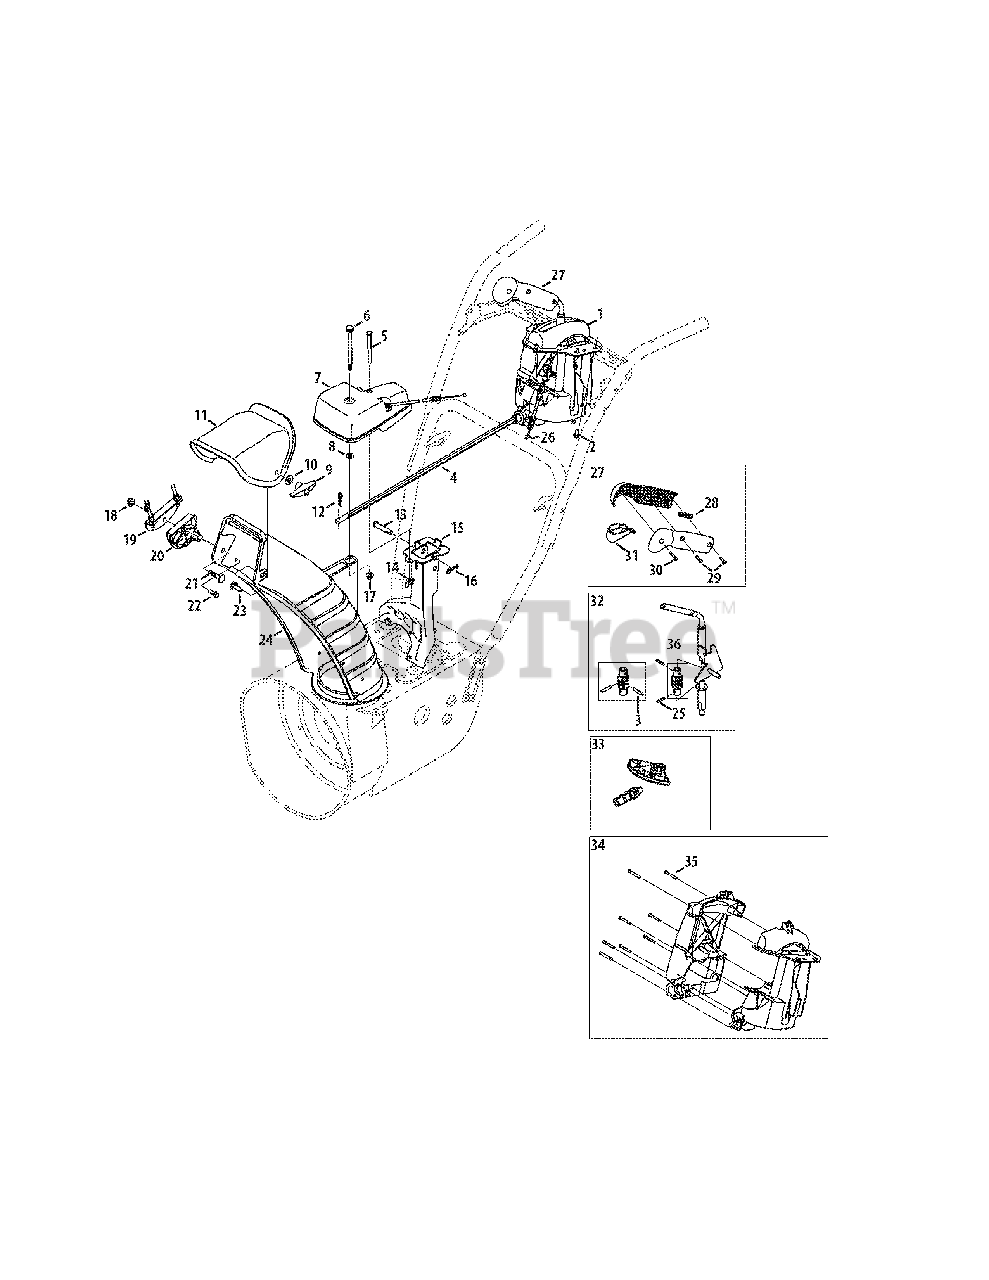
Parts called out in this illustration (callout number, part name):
1	4-Way Chute Control™ Assembly
2	Hi-Lo Screw, 1/4-15 x 0.5
3	Roll Pin
4	Chute Rod
5	Hex Screw, 1/4-20 x 3.00
6	Flange Shoulder Screw
7	4-Way Chute Gearbox Assembly
8	Flat Washer, .25 x .630 x .0515
9	Wing Knob
10	Flat Washer, .349 x .879 x .063
11	Upper Chute
12	Cotter Pin
13	Clevis Pin
14	Wing Nut, 1/4-20
15	Chute Support Bracket
16	Bow Tie Cotter Pin
17	Flange Lock Nut, 1/4-20
18	Flange Lock Nut, 5/16-18
19	Cable Bracket
20	Chute Tilt Cable Guide
21	Carriage Bolt, 5/16-18 x 1.50
22	Hi-Lo Screw, 1/4-15 x .75
23	Carriage Bolt, 5/16-18 x 1.0
24	Lower Chute
26	4-Way Cable
27	Handle Assembly
28	Handle Plunger
29	Screw, Mach., #8-32 x .750
30	Screw, #8 x 1.00
31	Handle Lever
32	Shift Assembly
33	Gear Set Assembly
34	Handle Housing Assembly
35	Screw, #8-18 x 1.250
36	Joint Block Assembly
